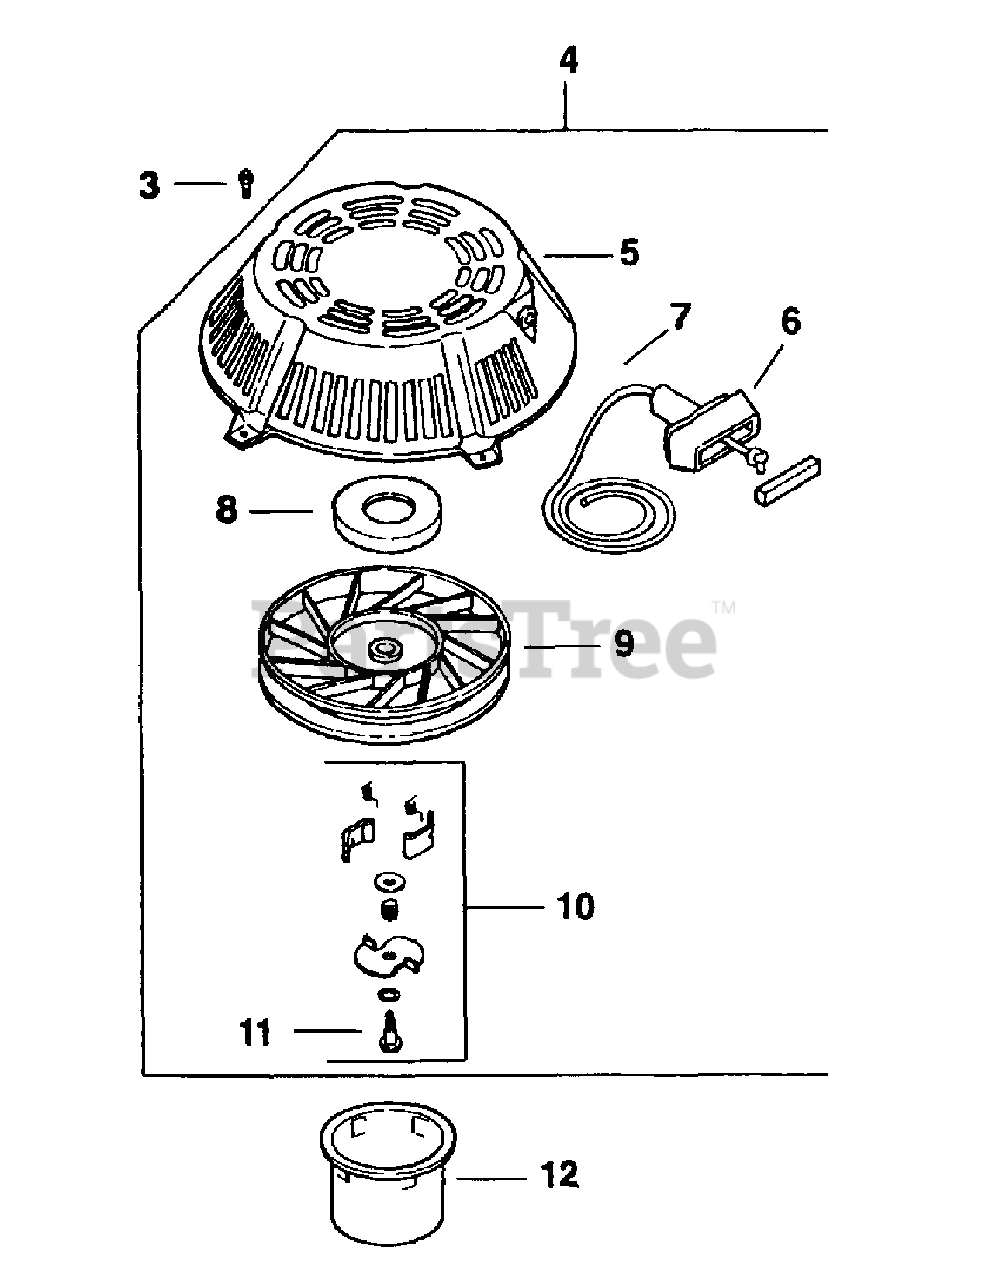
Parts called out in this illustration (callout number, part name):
3	Screw, Hex Flange
4	Starter, Retractable Assy.
5	Housing, Starter
6	Handle, Recoil Start
7	Rope, Starter
8	Spring & Keeper
10	Kit, Dog Repair
11	Screw
12	Cup, Drive
